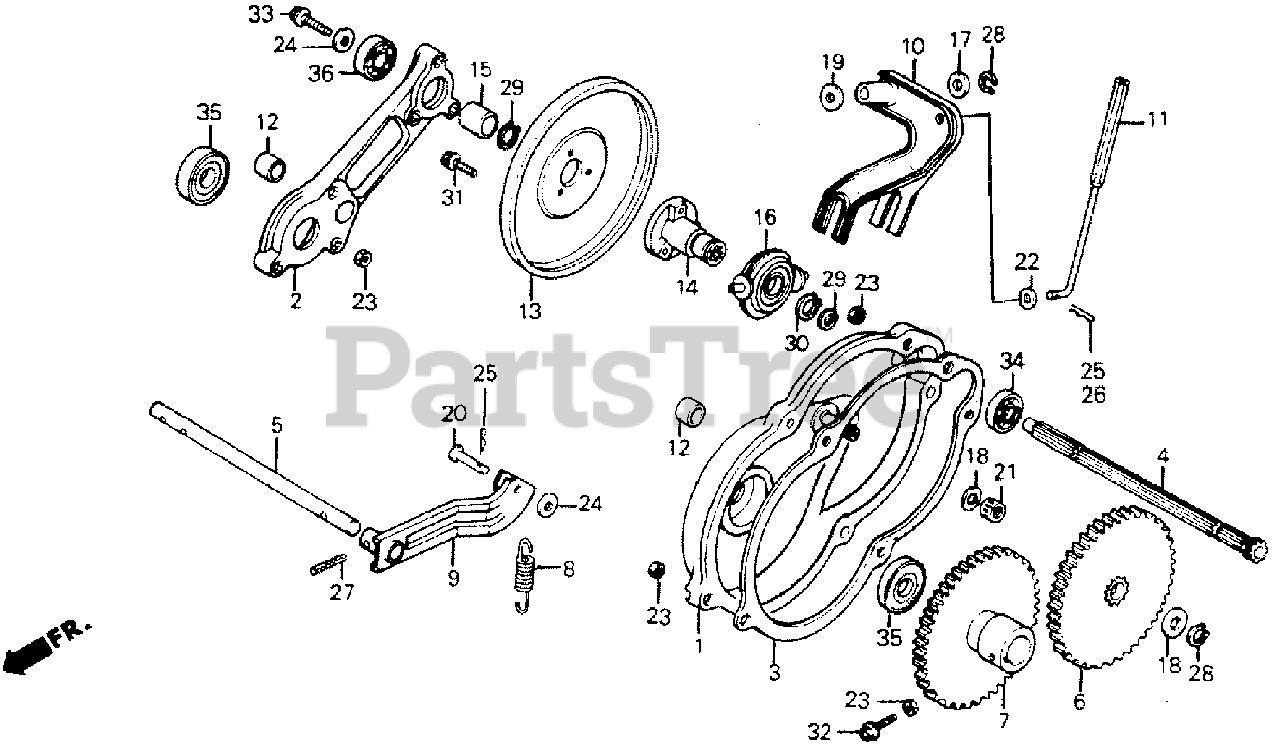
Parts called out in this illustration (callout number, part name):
1	CASE, L. TRANSMISSION (NOT AVAILABLE)
2	CASE, R. TRANSMISSION
2	CASE, R. TRANSMISSION (NOT AVAILABLE)
3	GASKET, TRANSMISSION CASE
4	SHAFT, FRICTION DISK
5	SHAFT, DISK HOLDER
6	GEAR, COUNTER
7	GEAR, FINAL (NOT AVAILABLE)
8	SPRING, DRIVE DISK RETURN (NOT AVAILABLE)
9	ARM, CLUTCH
10	ARM, CHANGE
11	JOINT, CHANGE
12	BUSH, DRIVE DISK SHAFT
13	DISK, FRICTION
14	BOSS, FRICTION DISK (NOT AVAILABLE)
15	COLLAR, FRICTION
15	COLLAR, FRICTION (NOT AVAILABLE)
16	ROLLER (NOT AVAILABLE)
17	WASHER, THRUST (12MM)
18	WASHER C, THRUST (12MM) (0.7)
19	WASHER, THRUST (12MM)
20	PIN, CLUTCH ARM
21	BEARING, NEEDLE (12MM)
22	COLLAR, CHANGE JOINT
23	NUT, HEX. (6MM)
24	WASHER, PLAIN (6MM)
25	PIN, LOCK (6MM)
27	PIN, SPRING (6X25)
28	CIRCLIP (OUTER) (12MM)
29	CIRCLIP (OUTER) (15MM)
30	CIRCLIP (OUTER) (22MM)
31	BOLT, FLANGE (6X12)
32	BOLT, FLANGE (6X16)
33	BOLT, FLANGE (6X16)
34	BEARING, RADIAL BALL
35	BEARING, RADIAL BALL (6004UU)
36	BEARING, RADIAL BALL (6201UU)
